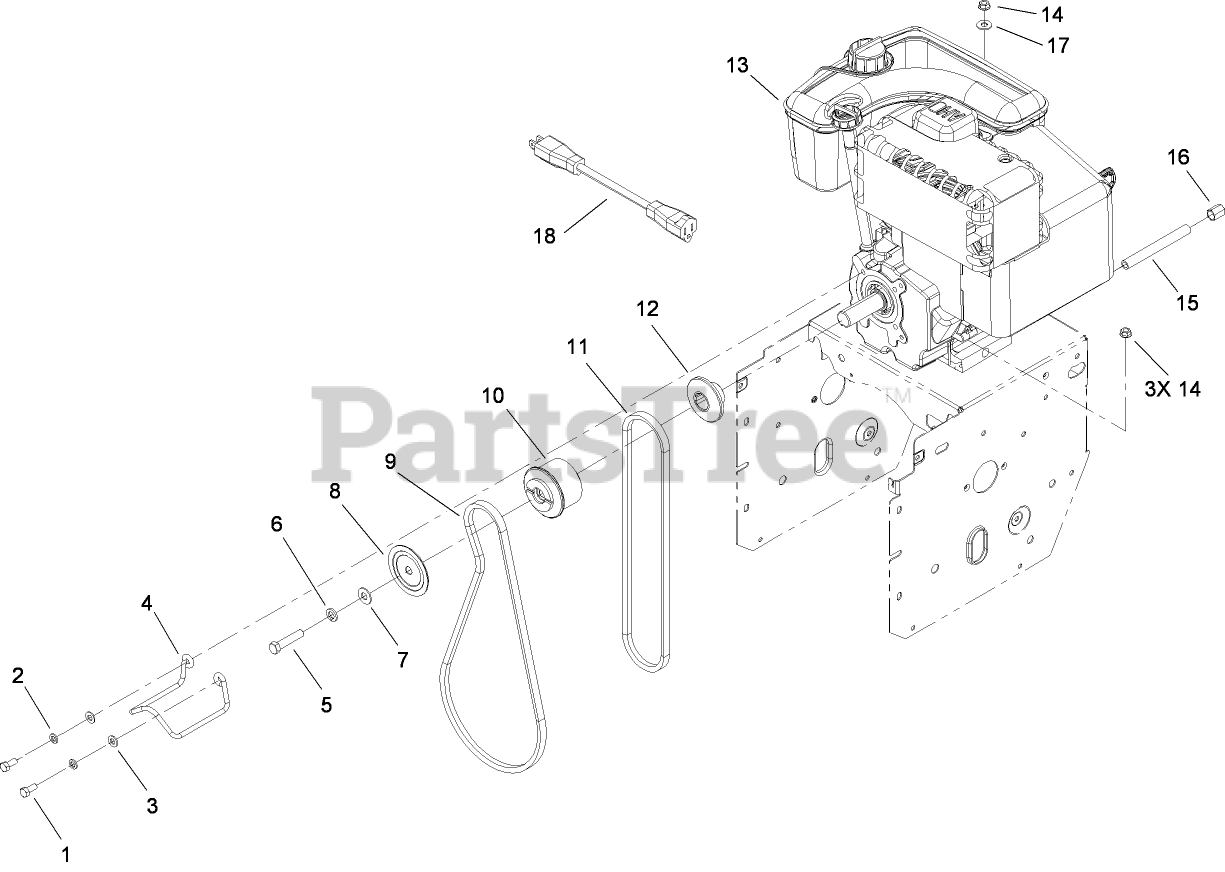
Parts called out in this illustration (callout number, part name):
1	SCREW-HH
2	WASHER-LOCK
3	WASHER-PLAIN
5	SCREW-HH
6	WASHER-LOCK
7	WASHER-FLAT
8	SHEAVE-HALF, IMPELLER
9	BELT-V
10	PULLEY-ENGINE, CENTER
11	V BELT-TRACTION
12	SHEAVE-HALF, TRACTION
13	Loose Parts Package
14	NUT-HF
15	NIPPLE-PIPE
16	CAP-PIPE
17	WASHER-FLAT
18	CORD-EXTENSION (only on: 38078)
